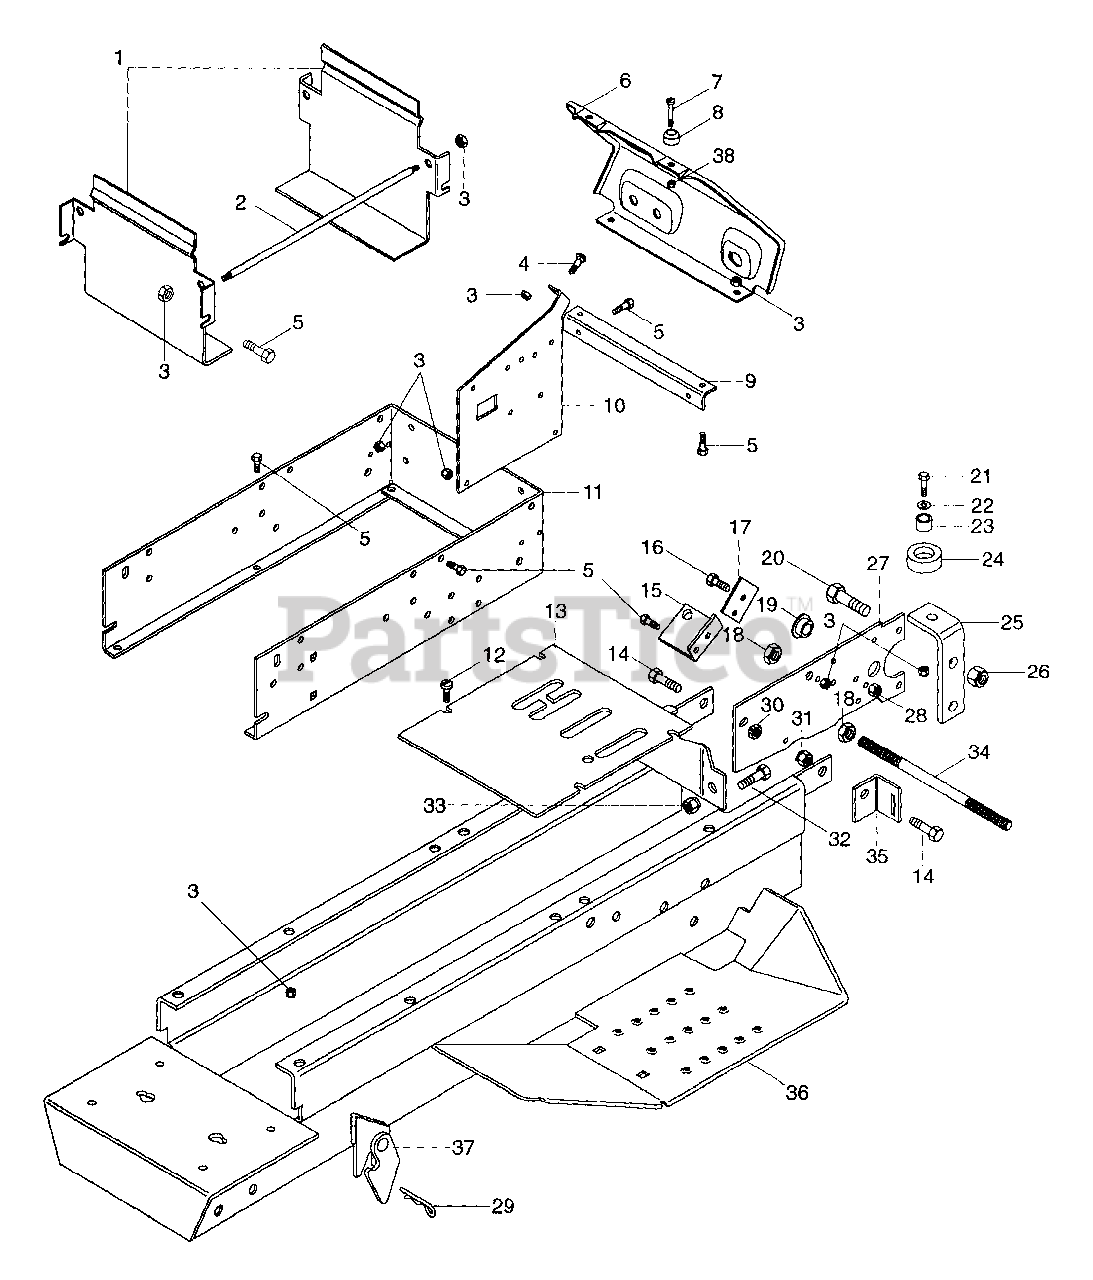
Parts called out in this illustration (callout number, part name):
1	Tank Support
2	Rod, Tank
3	Nut-Locking-Nylon .250-20 Grade 2
4	Screw-Machine .25-20
5	Bolt-Hex .25-20 x .75 Grade 5
6	Instrument Panel, Silkscreen
7	Screw-Machine 6-32 x .625
8	Bumper
9	Bracket, Instrument Panel
10	Bracket, Instrument Panel Left Hand
10	Bracket, Instrument Panel Right Hand
11	Support, Instrument
12	Screw-Tapping .250-20 x .625
13	Plate, Manual Control Cover
13	Plate, Hydraulic Control Cover
14	Bolt-Hex .38-16 x 1.25 Grade 5
15	Bracket, Interlock Switch
16	Bolt-Hex .31-18 x .75 Grade 5
17	Bracket, Bushing Lock
18	Nut .50-13
19	Bushing-Flange .762 x 1.0 x .580 x 1.48
20	Bolt-Hex .50-13 x 1.50 Grade 5
21	Bolt-Hex .25-20 x 1.25 Grade 5
22	Washer-Flat-Steel .312 x .734 x .065
23	Bushing-Sleeve .265 x .375 x .250
24	Bumper, Seat
25	Bracket, Rear Hitch
26	Nut-Locking-Nylon .50-13 Grade 5
27	Plate, Forward-Reverse Mounting
28	Nut-Locking-Nylon .312-18 Grade 2
29	Pin-Hair-Internal .15 x 2.937
30	Nut-Locking-Center .625-10 Grade 2
31	Nut-Locking-Nylon .375-16 Grade 2
32	Bolt-Hex .50-20 x 1.50
33	Nut-Hex .5O-20
34	Rod, Frame External Brace
35	Bracket, Fender Hold-Up
36	Weldment, Frame
37	Weldment, Mower Bracket Right Hand
37	Weldment, Mower Bracket Left Hand
38	Nut-Locking-Machine 6-32
